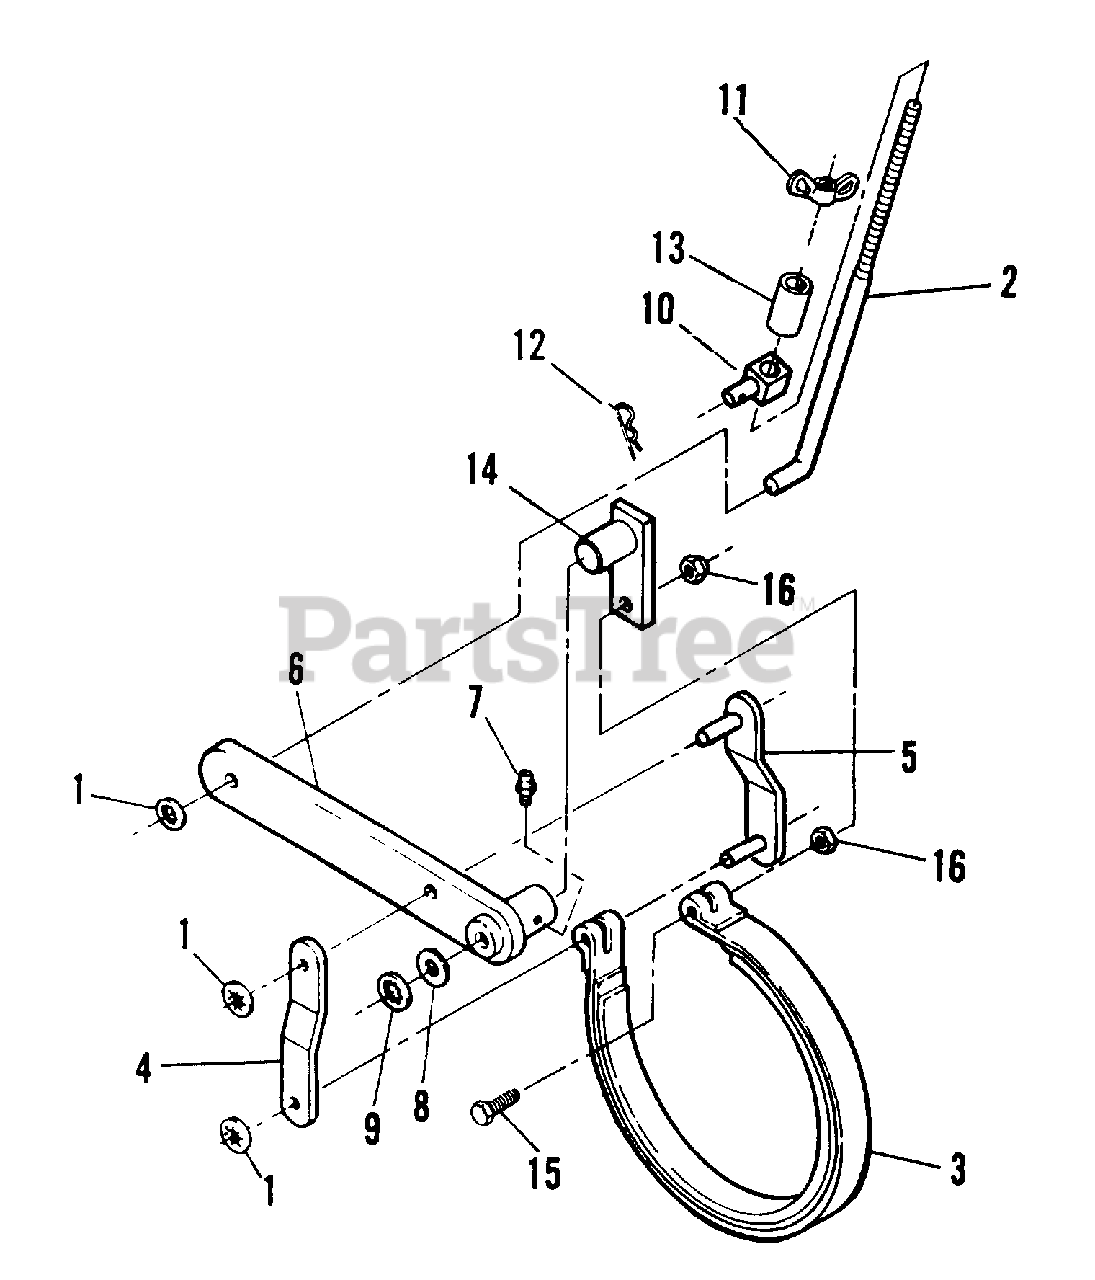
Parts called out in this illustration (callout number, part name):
1	RETAINER, 3/8"
2	ROD, Brake
3	BAND, Brake, 6"
4	PLATE, Brake Link
5	LINK, Brake
6	BRAKE, Lever
7	ZERK, 1/4 - 28, Straight
8	BUSHING, Machinery, 5/8"
9	RETAINER, 5/8"
10	SWIVEL, Brake Link
11	WING NUT, 3/8" C, Nylon Lock
12	PIN, 3/32" x 1" Cotter
13	SPACER
14	BRAKE STUD WLD
15	BOLT, 3/8" - 16 x 2", Hex
16	NUT, 3/8 C, Hex
